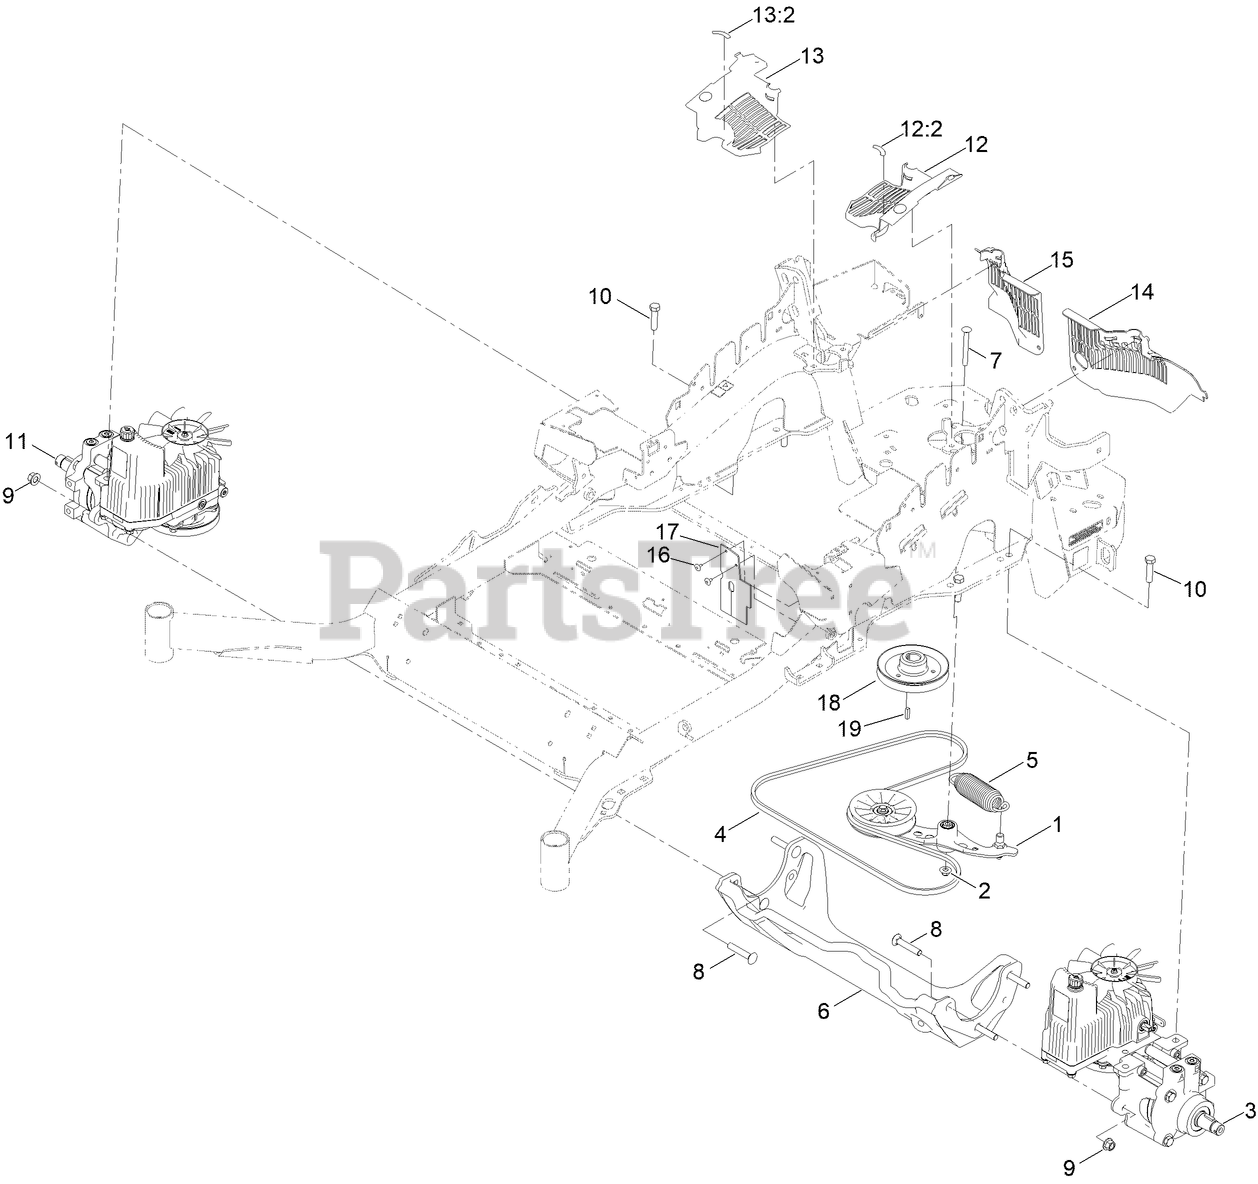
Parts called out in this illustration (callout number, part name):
1	PUMP IDLER ASM
2	NUT-FLANGE, NI
3	HYDRO-LH
4	BELT-V
5	SPRING-EXTENSION
6	CRADLE-HYDRO
7	BOLT-SHOULDER, CARRIAGE
8	SCREW-CARR
9	NUT-LOCK
10	SCREW-HH
11	HYDRO-RH
12	LH HYDRO GUARD ASM
12:2	DECAL-OIL, HYDRO
13	RH HYDRO GUARD ASM
13:2	DECAL-OIL, HYDRO
14	GUARD-HYDRO, REAR (LH)
15	GUARD-HYDRO, REAR (RH)
16	RIVET-POP
17	DEFLECTOR-AIR FLOW
18	SHEAVE, W/HUB
